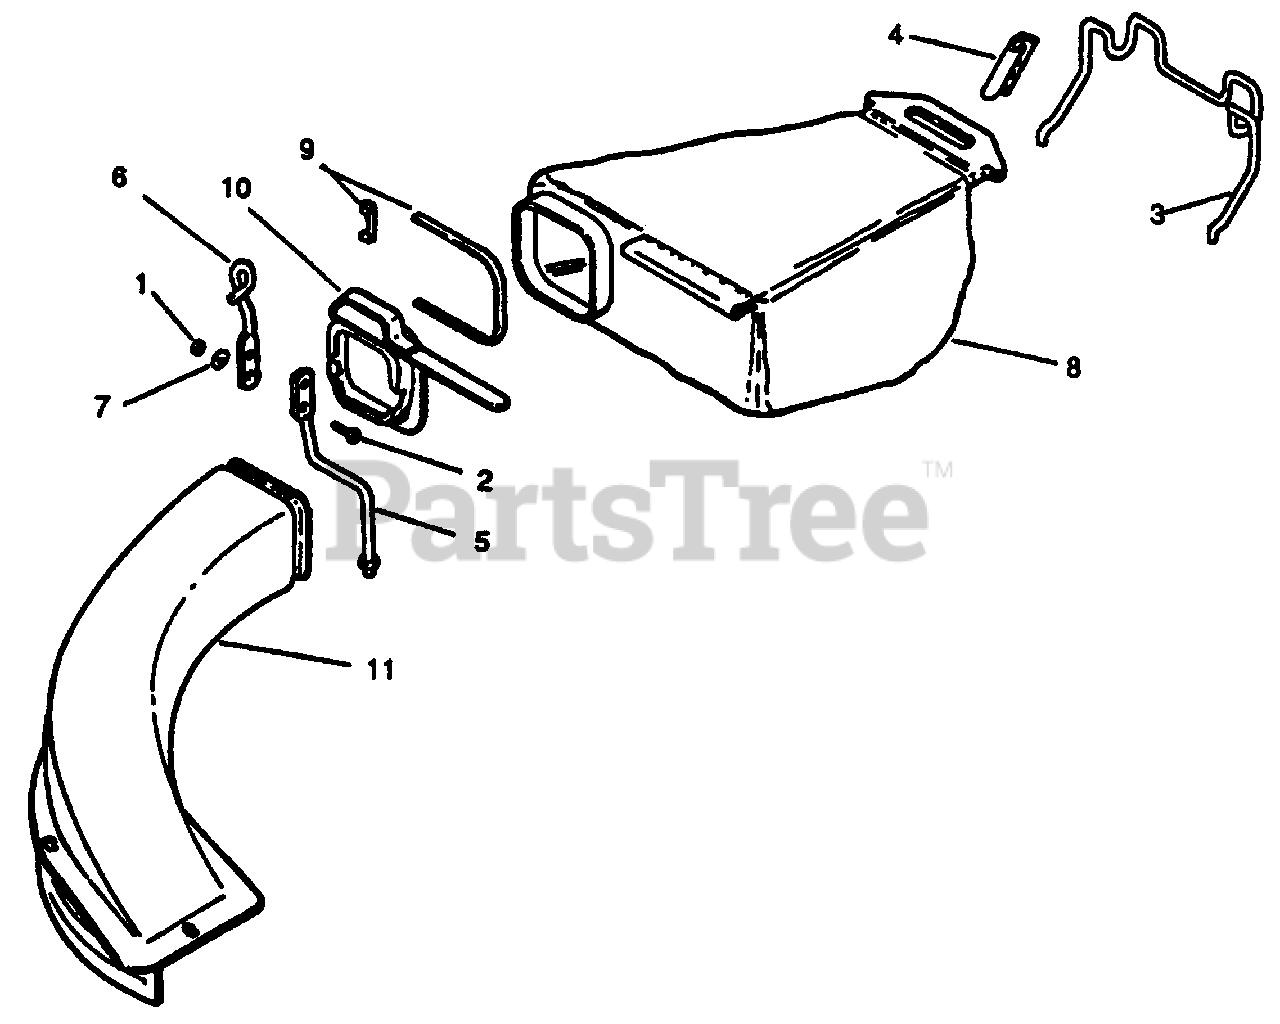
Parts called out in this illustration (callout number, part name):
1	Locknut
2	Screw
3	Wide Hanger
4	Hanger Clamp
5	Chute Support
6	Rope Guide
7	Washer
8	Bag Assembly (Inc. 9)
9	Strap & Lock Assembly
10	Adaptor Assembly
11	Chute
